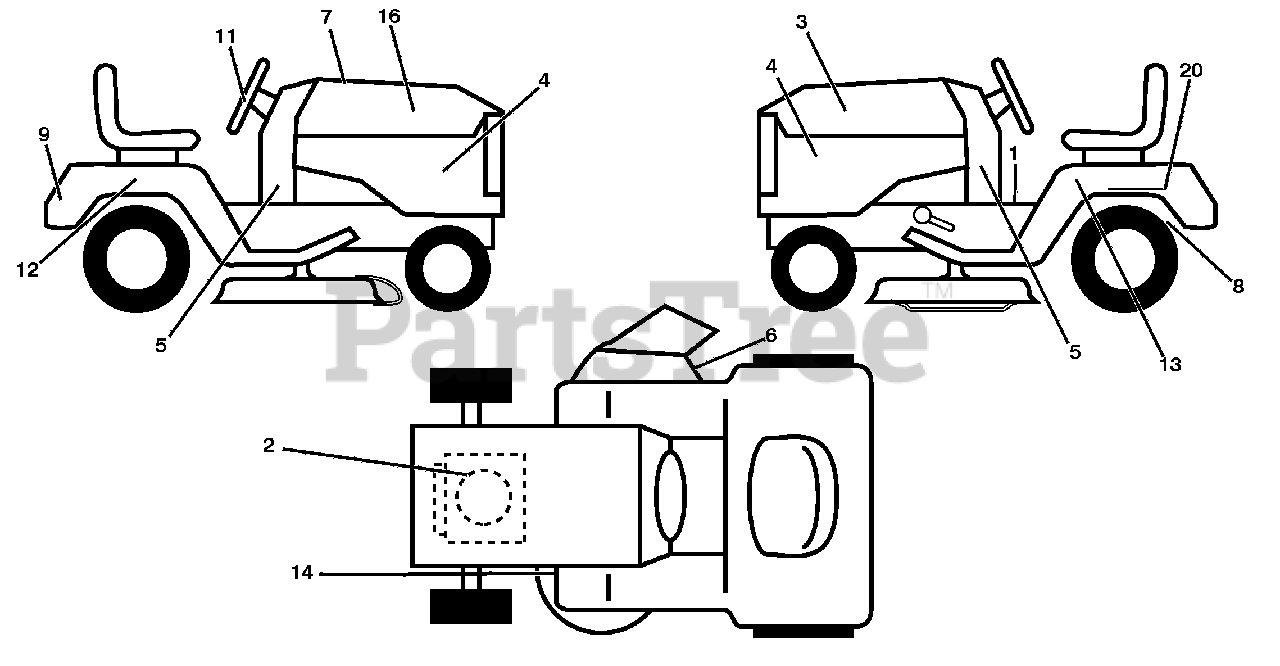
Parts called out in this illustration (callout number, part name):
1	Decal Fend. INS/WRN
2	Decal Engine H.P.
3	Decal Hood LH
4	Decal Side Panel
5	Decal Lwr Dash
6	Decal Warning, Keep Hand Away
7	Decal Replacement Parts
8	Decal Bypass
9	Decal Fender Logo
11	Decal Ins Strg Whl
12	Decal Fender SD RH
13	Decal Fender SD LH
14	Decal V-Belt Schematic
16	Decal Hood Rh
20	Decal Bat Dan/Psn
20	Pad Footrest LH
20	Pad Footrest RH
20	Manual Operator's E&F
20	Manual Parts
